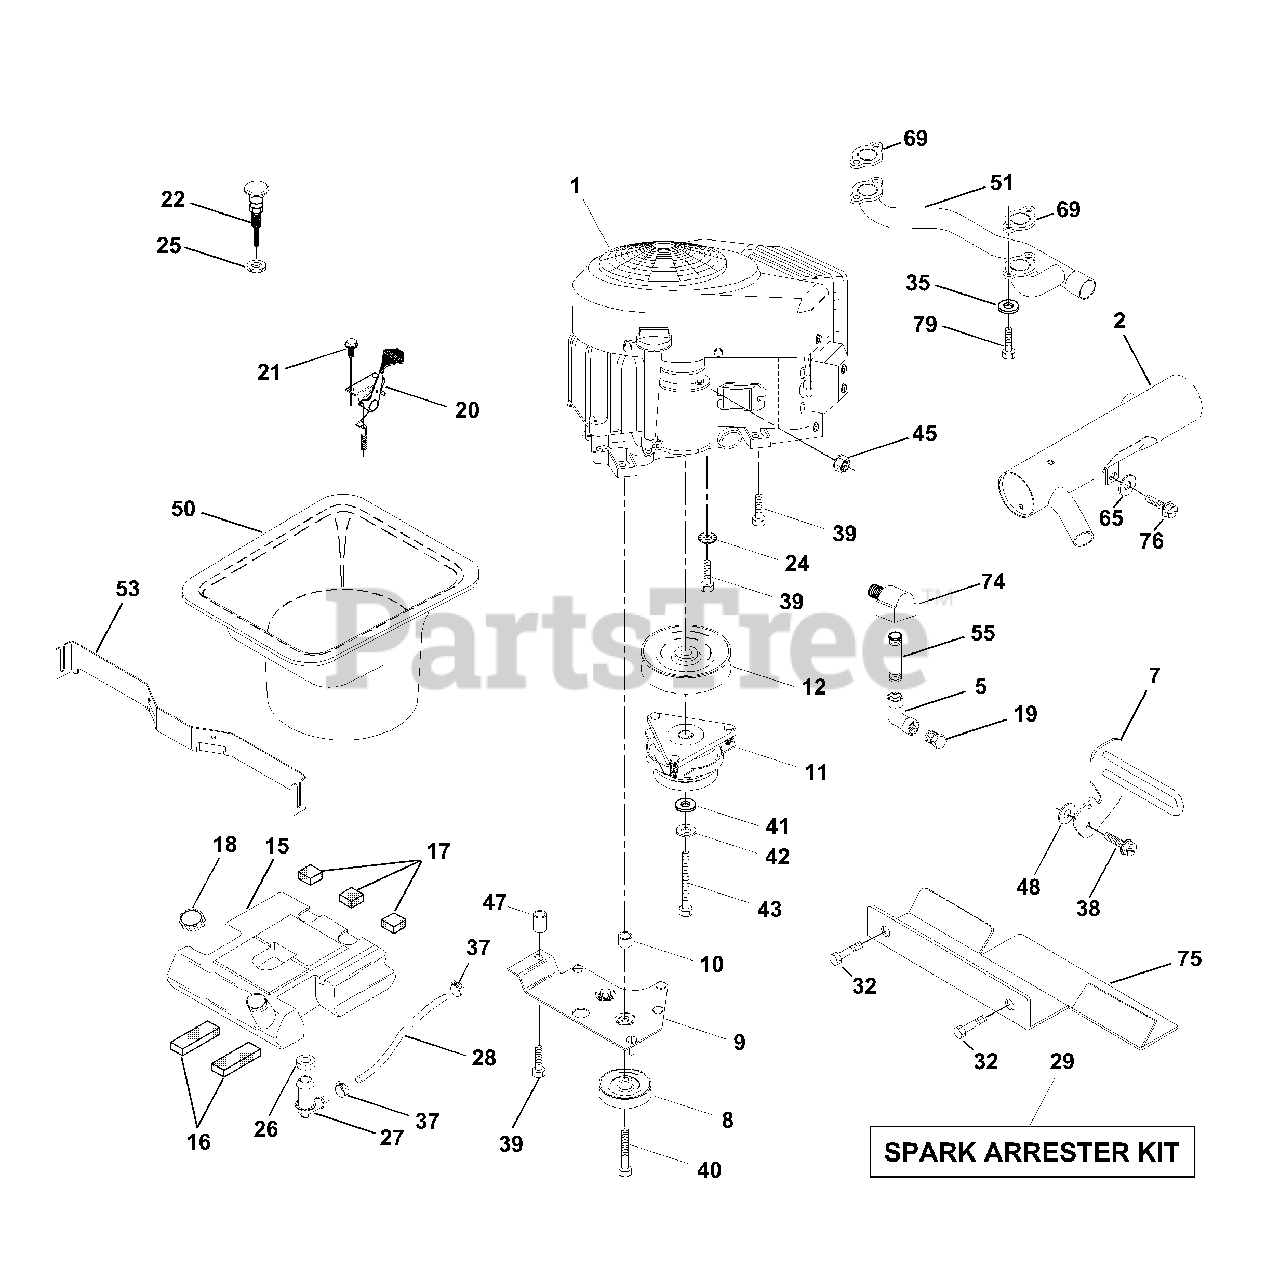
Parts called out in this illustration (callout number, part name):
2	Muffler Side
5	Elbow STD 90 Degree 3/8 - 18 NPT
7	Muffler Assembly Guard
8	Pulley V-Idler
9	Keeper Asm. Belt Engine VGT96
10	Bushing
11	Clutch Electric
12	Pulley Engine VGT Elect Clutch
15	Tank Fuel Rear 3.50 YT/GT 96
16	Pad Spacer
17	Pad Spacer
18	Cap Asm Fuel W/Sym Vented
19	Plug Oil Drain
20	Control Throttle
21	Screw Hex Thd Cut 1/4 - 20 X 5/8
22	Control Choke
24	Washer Ext Tooth 3/8
25	Nut , Keps 3/8-24 UNF
26	Bushing
27	Stem Tank Fuel
29	Spark Arrester Kit
32	Screw Thdrl 5/16-18 x 1/2
35	Washer Lock Hvy HLCL Spr 5/16
37	Clamp Hose
38	Screw 3/8-16 x 1-1/4
39	Screw TT 3/8-16 x 2-1/4 UNC
40	Screw TT 3/8-16 x 4 UNC
41	Washer 1-1/2 OD X 15/32 ID X .250
42	Washer Lock 7/16
43	Bolt, Hex 7/16-20 x 4-1/4 5 Ga. 1.38
45	Nut Keps Hex 1/4-20 UNC
47	Spacer Engine CV22 Round PM
48	Washer 13/32 x 1-1/4 x 7 Ga.
50	Duct Air Intake
51	Manifold VGT
53	Rod Support Hood Duct
55	Nipple, Pipe 3/8 NPT x 4-1/2
65	Washer 13/32 x 1 x 14 Ga.
69	Gasket
74	Elbow Street Brass
75	Shield Heat Intek VGT
76	Screw Hexwsh Thdrl 3/8-16 x 3/4
79	Screw Hex Hd Cap 5/16-18 x 3/4
